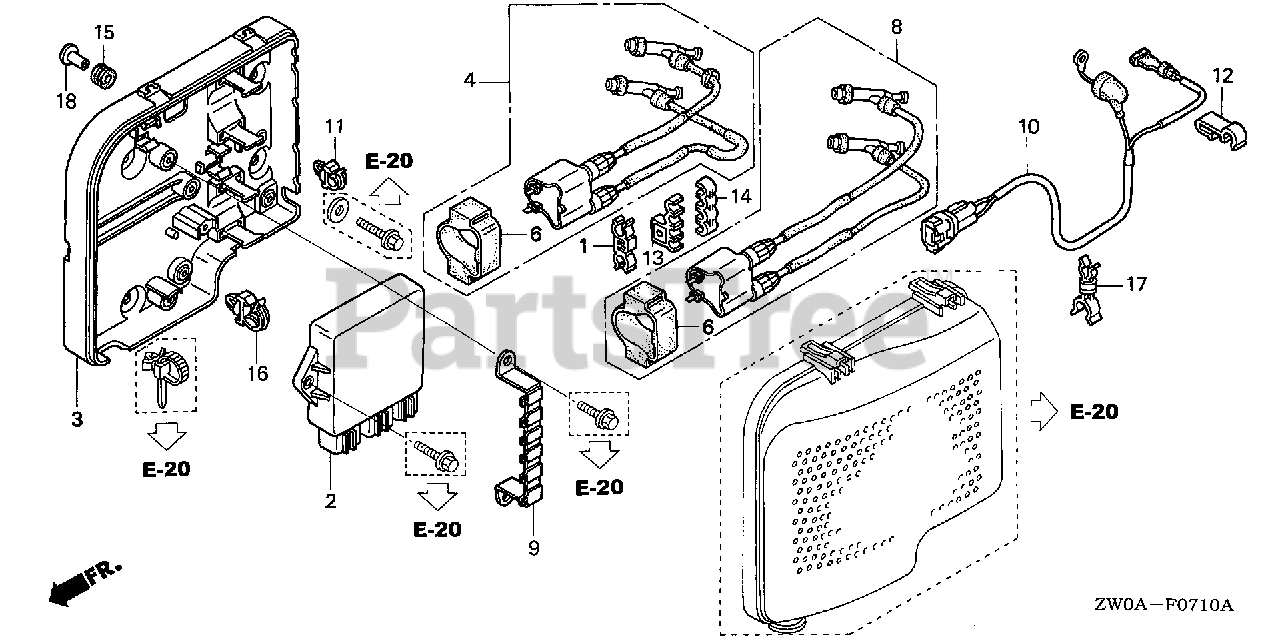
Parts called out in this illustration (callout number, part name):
1	CLAMP, R. INTERCOOLER
2	MODULE, IGNITION CONTROL (CDI)
3	CASE, IGNITION CONTROL MODULE (CDI)
4	COIL ASSY., IGNITION (1)
6	SUSPENSION, IGNITION COIL
8	COIL ASSY., IGNITION (2)
9	BRACKET, CONNECTOR
10	WIRE, SWITCH
11	CLAMP, WIRE
12	CLAMP, WIRE
13	CLAMP B, IGNITION WIRE
14	GROMMET, IGNITION WIRE
15	GROMMET, CASE (LOWER)
16	CLIP, WIRE HARNESS
17	CLIP, SWITCH CORD
18	COLLAR, MODULE IGNITION CONTROL CASE (CDI)
